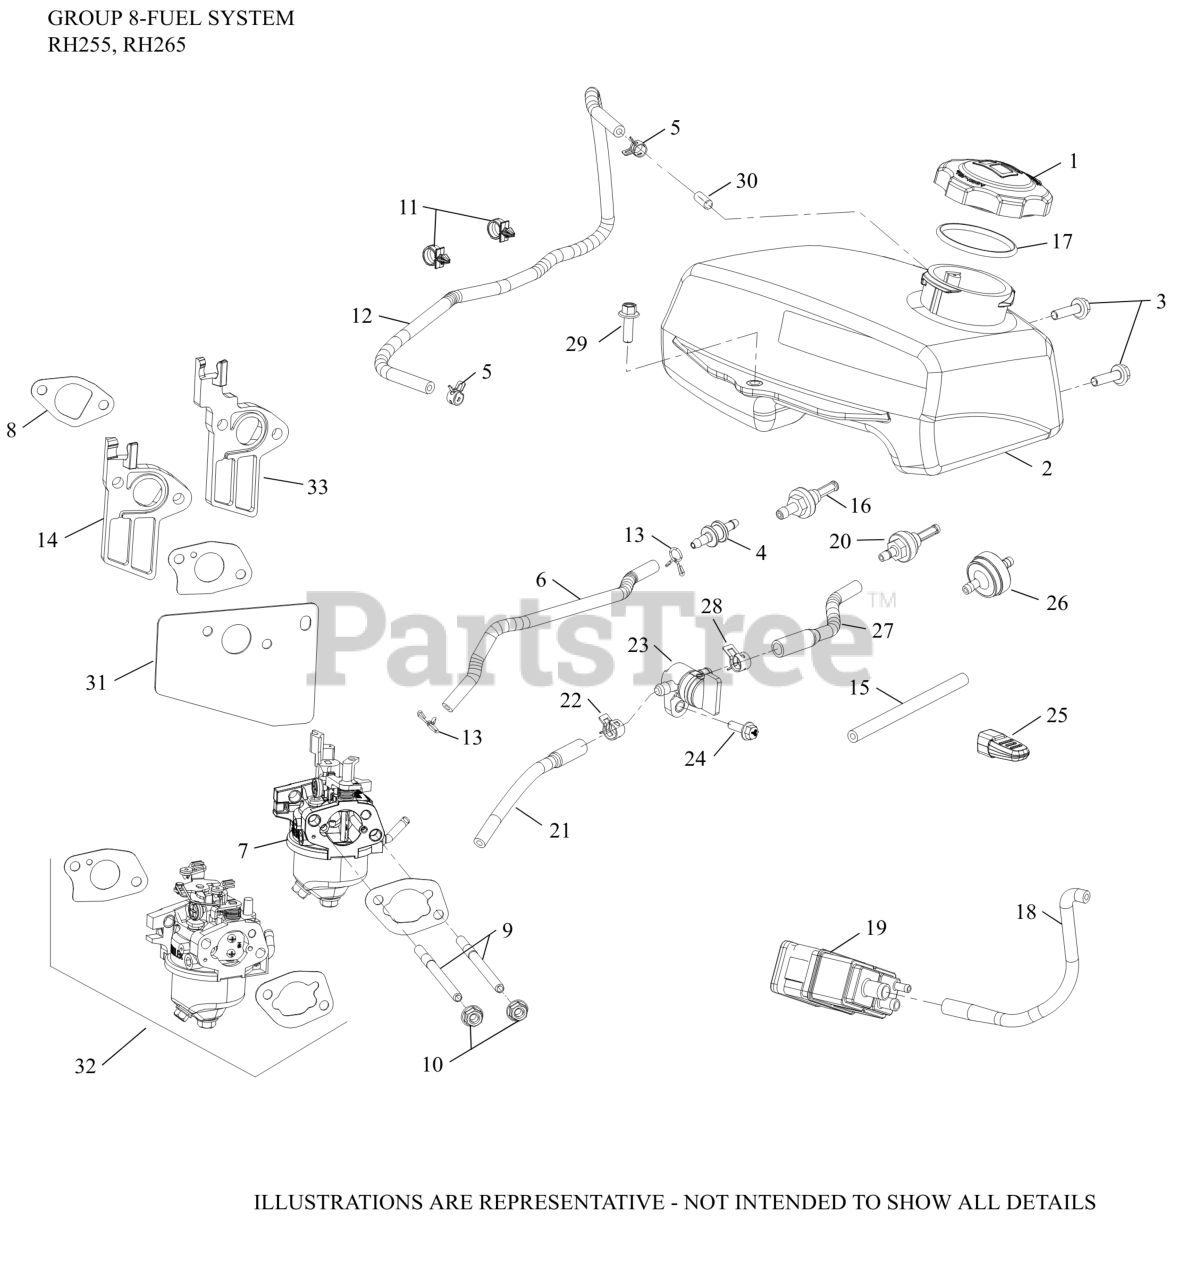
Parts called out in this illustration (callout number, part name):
1	CAP ASSEMBLY, FUEL
2	TANK, ASSEMBLY (EPA)
3	SCREW, M6 X 22
6	HOSE, FUEL LOW-PERMEATION
7	KIT,CARB (HUAYI)
8	KIT, INTAKE GASKET
9	STUD, CARBURETOR
10	NUT, HEX FLANGE (M6) - USE 14 100 16-S
10	NUT, HEX FLANGE LOCK (M6)
11	CLIP, FUEL HOSE
12	HOSE, EVAPORATIVE
13	CLAMP, FUEL HOSE
14	INSULATOR, CARBURETOR
17	SEAL, FUEL CAP
20	FITTING, FUEL ASSY
25	KNOB, CHOKE (YELLOW)-USE 18 536 11-S
29	SCREW, M6 X18
NI	KIT, CARBURETOR REPAIR (HUAYI)
NI	KIT, HIGH ALTITUDE MAIN JET
NI	KIT, HIGH ALTITUDE
